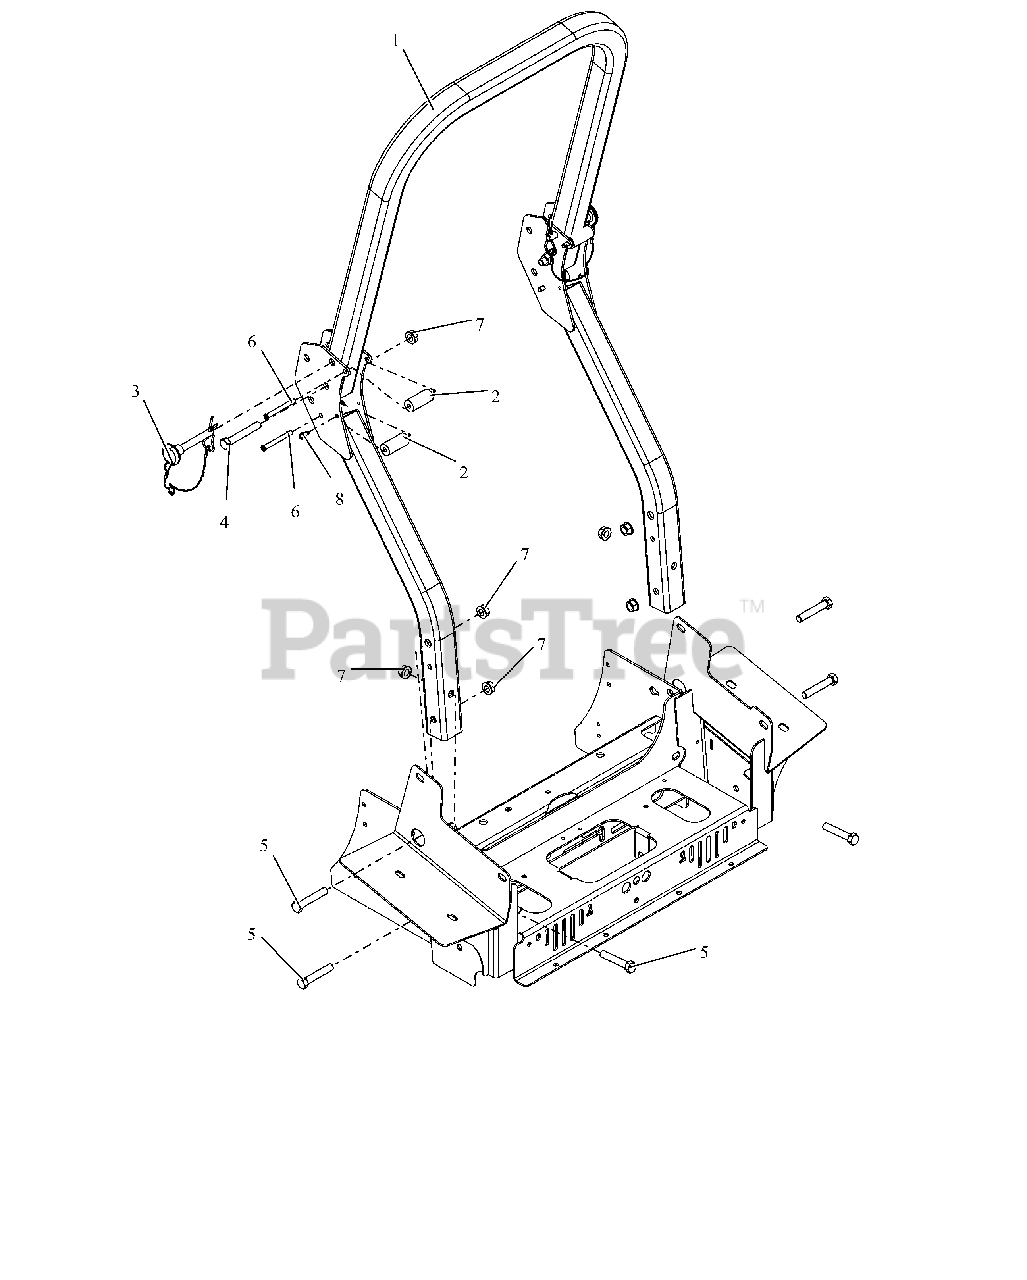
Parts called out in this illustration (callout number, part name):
1	ROPS, PT200/400 REPLACEMENT
2	BUMPER, ROPS ANTI-VIBRATION
3	PIN, ROPS W/LANYARD
4	BLT,HEX .50-13X3.25 G5 ZCC
5	BLT,HEX .50-13X2.75 G5 ZCC
6	PIN, SLIC .312 X 2.570
7	NUT-LK-CTR-FLG .500-13 GG ZCC
8	SCR-TAP .25-20X.50 HWH TR YWZ
